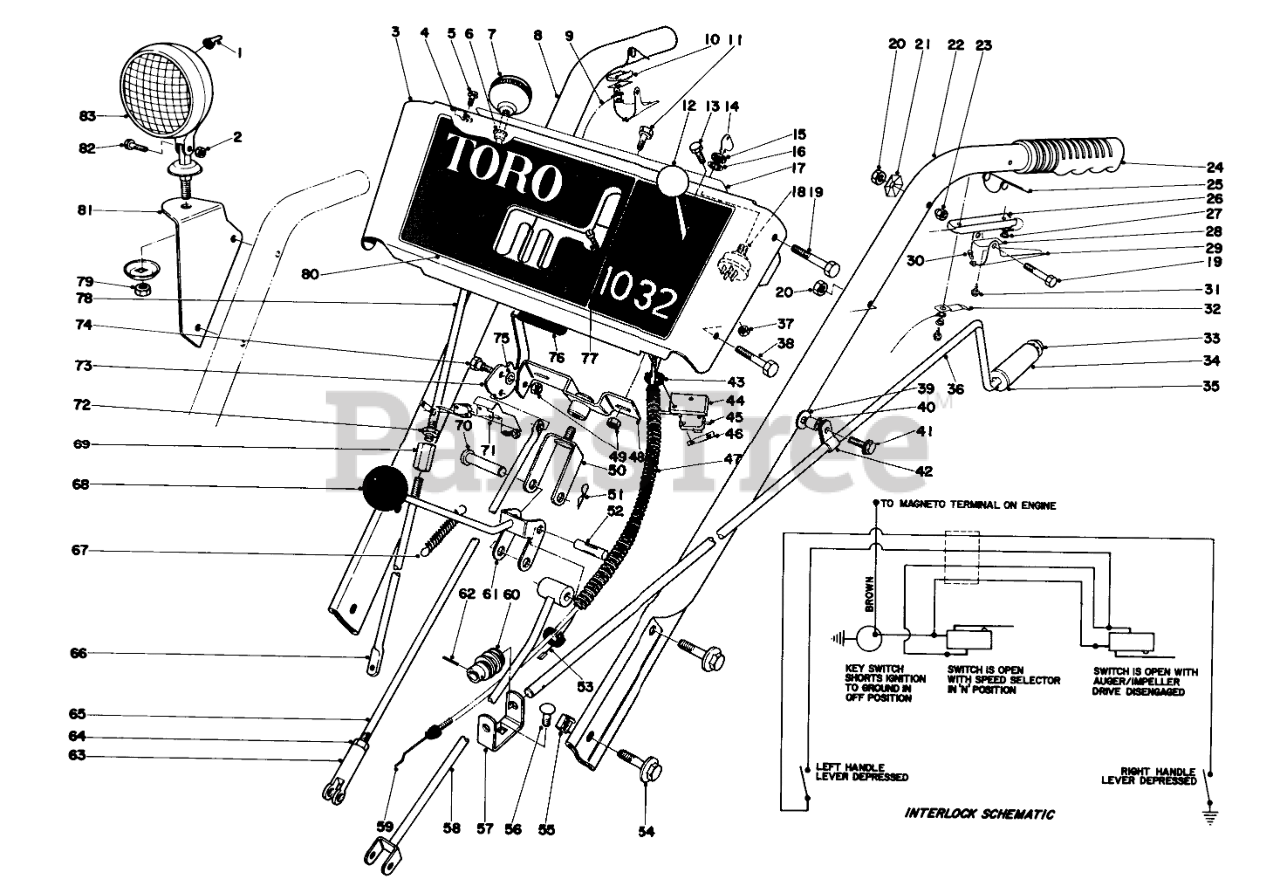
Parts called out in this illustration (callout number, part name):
1	BOOT-SWITCH
2	NUT-HEX, SIDE DEFORM
3	Escutcheon Plate (Incl.Ref. #17&80)
4	PLASTIC CLIP
5	SCREW-HWHTF
6	NYLINER #6LI-FF TYPE 7
7	KNOB-LEVER
8	Handle Right
9	Wire Harness Interlock
10	Insulator
11	SCREW-HH
12	KNOB-CONTROL
13	HEX HEAD SEMS 10-24X1/2
14	Key
16	WASHER-TOOTH, INTERNAL
17	Decal-Escutcheon Back
18	SWITCH-STARTER
19	SCREW-HH
20	NUT-LOCK, CONE
21	Washer
22	Handle Left
23	NUT-CAP
24	Grip Handle
25	INTERLOCK SPRING
26	Insulator
27	WASHER INSULATOR
28	INTERLOCK CONTACT
29	Safety Lever
30	1/4 PLASTIC RIVET
31	Screw
32	CONTACT BRACKET
33	RETAINER-PUSH ON
34	CHUTE CONTROL GRIP
35	WASHER-FLAT
36	ROD CHUTE CONTROL
37	Nut
38	SCREW-HH
39	Washer
40	Space
41	He Ha. Screw
42	R-CLAMP
43	RING FITTING
44	SWITCH MTG PAD
45	MICRO SWITCH
46	NUT-SPEED
47	Cover Harness
48	SWIVEL BLOCK WA
49	NUT-LOCK, CONE
50	Pivot Bracket
51	PIN-HAIR
52	3/8 X 1-1/4 ROL
53	STRT MTR-SOLNOID WIRE
54	SCREW-HHF
55	Retained Nut
56	SCREW-CARR
57	WORM BRACKET
58	Trunnion
59	Throttle Contrl
60	GEAR-WORM, CHUTE
61	Rod Shift
62	PIN-SPRING
63	Clevis
64	NUT-HJ
65	DRAG LINK
66	LOWER WHL CLUTCH ROD
67	CONT ROD SPRING 0
69	WHL ROD COUPLING
70	PIN-CLEVIS
71	SWITCH BRKT
72	NUT-HJ
73	Auger Clutch Handle
74	SCREW-SHOULDER
75	WASHER-PLAIN
76	AUGER CLUTCH HND GRIP
77	SCREW-SPH
78	Rod Wheel Clutch
79	NUT-HEX
80	Decal-Escutcheon
81	Lamp Mount
82	SCREW-HH
83	HEADLAMP ASM
